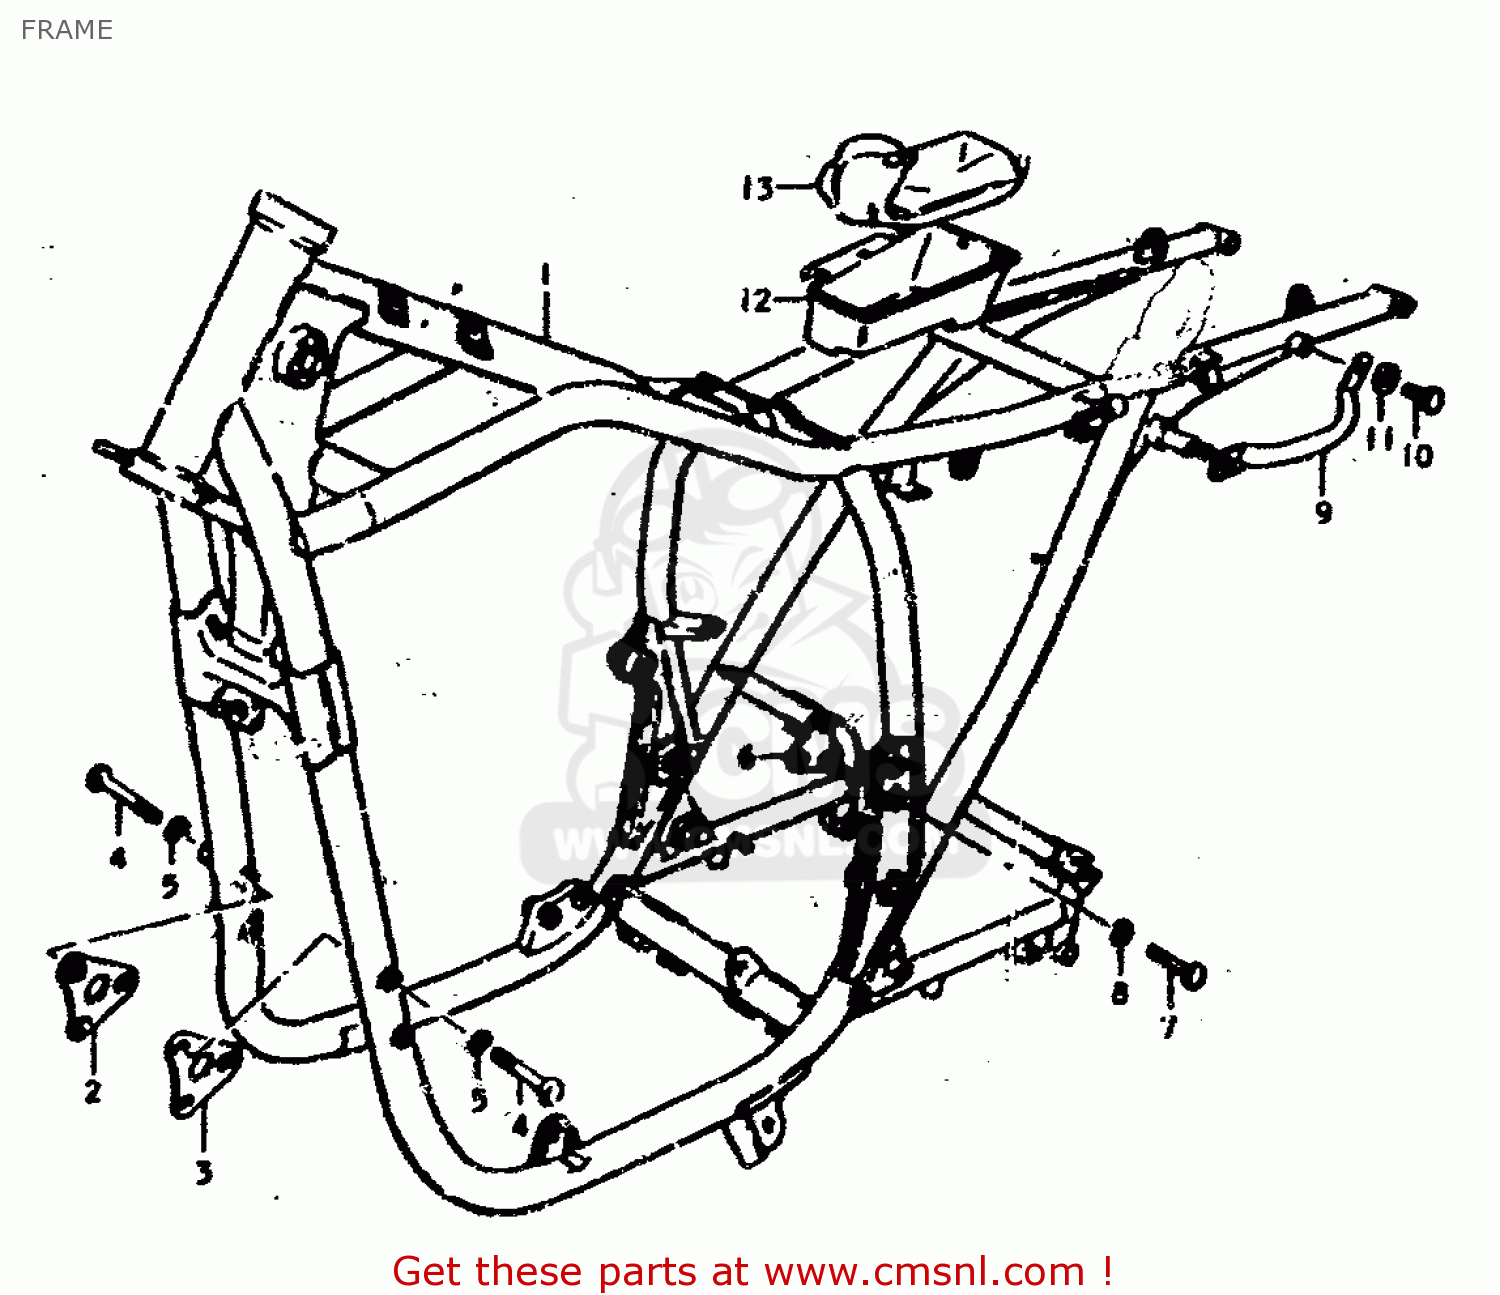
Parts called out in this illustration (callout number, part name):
1	FRAME
2	PLATE,ENGINE MOUNTING
3	PLATE,ENGINE MOUNTING
4	BOLT
5	LOCK WASHER
6	PLATE,ENGINE MOUNTING
7	BOLT 8X40
8	LOCK WASHER
9	GRIP,FRAME HANDLE
10	BOLT
11	LOCK WASHER
12	HOLDER,TOOL
13	TOOL SET
